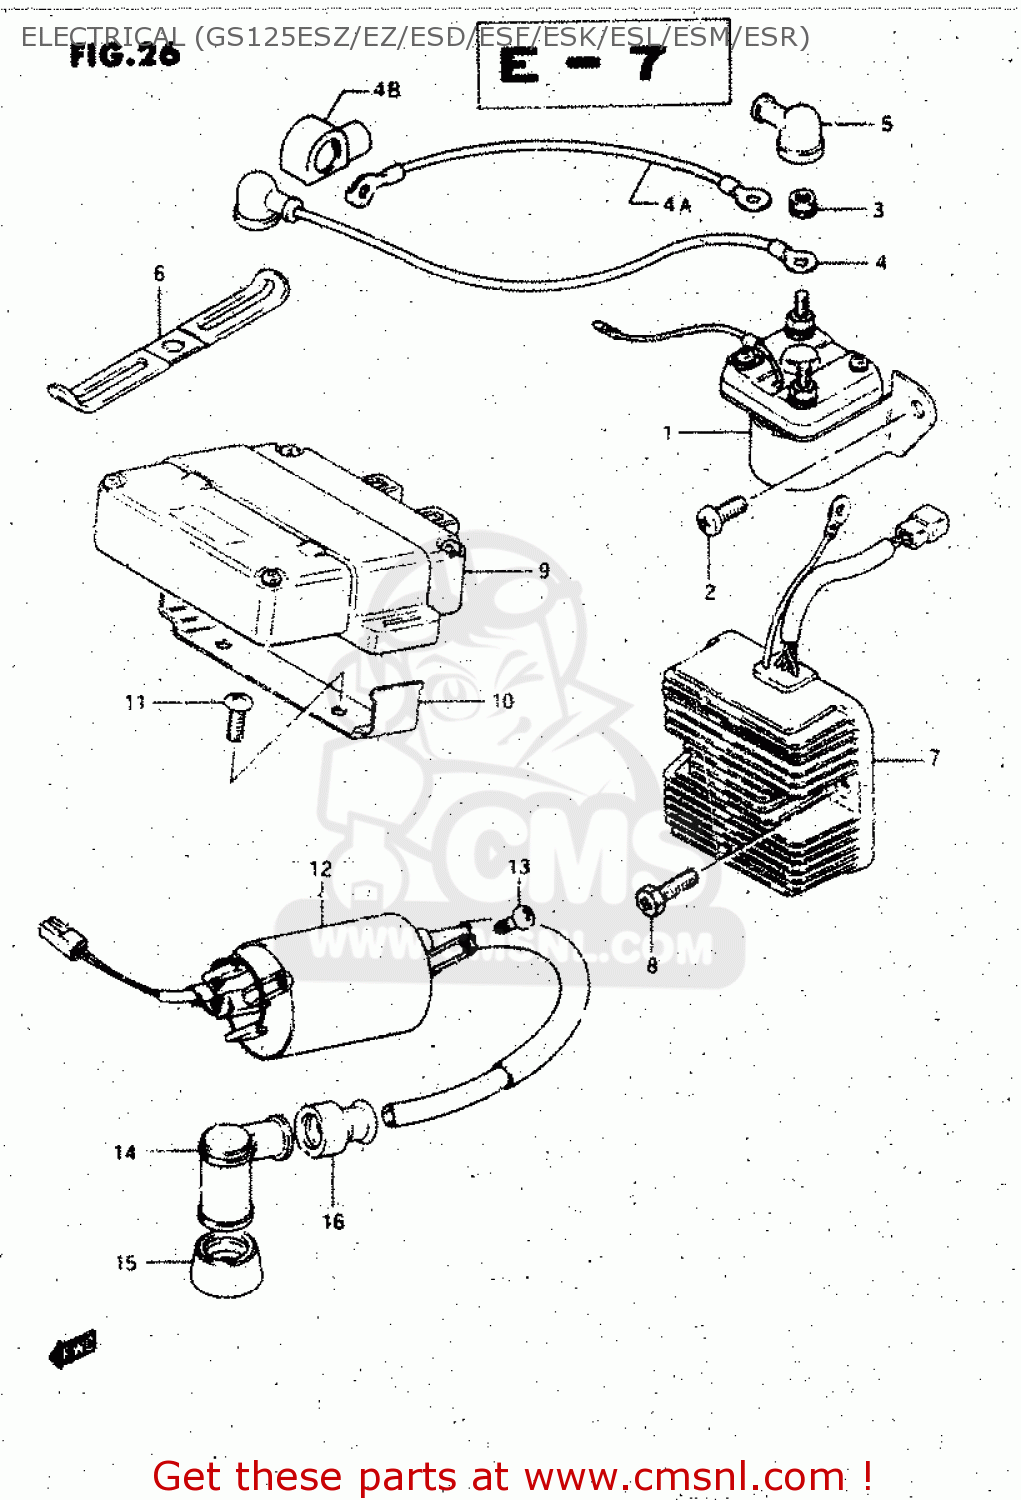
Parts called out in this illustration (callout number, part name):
1	RELAY ASSY,STARTING MOTOR
2	SCREW
3	NUT
4	WIRE,STARTER MOTOR
4A	WIRE,STARTER MOTOR LEAD
4B	CAP,STARTER MOTOR TERMINAL
5	CAP,STARTER MOTOR TERMINAL
6	CLAMP,WIRING HARNESS
7	RECTIFIER ASSY
8	BOLT(6X20)
9	IGNITOR UNIT
10	BRACKET, IGNITER
11	SCREW, PLATE
12	COIL ASSY,IGNITION
13	SCREW
14	CAP,SPARK PLUG
15	SEAL,SPARK PLUG CAP
16	SEAL,HIGH TENSION CORD
